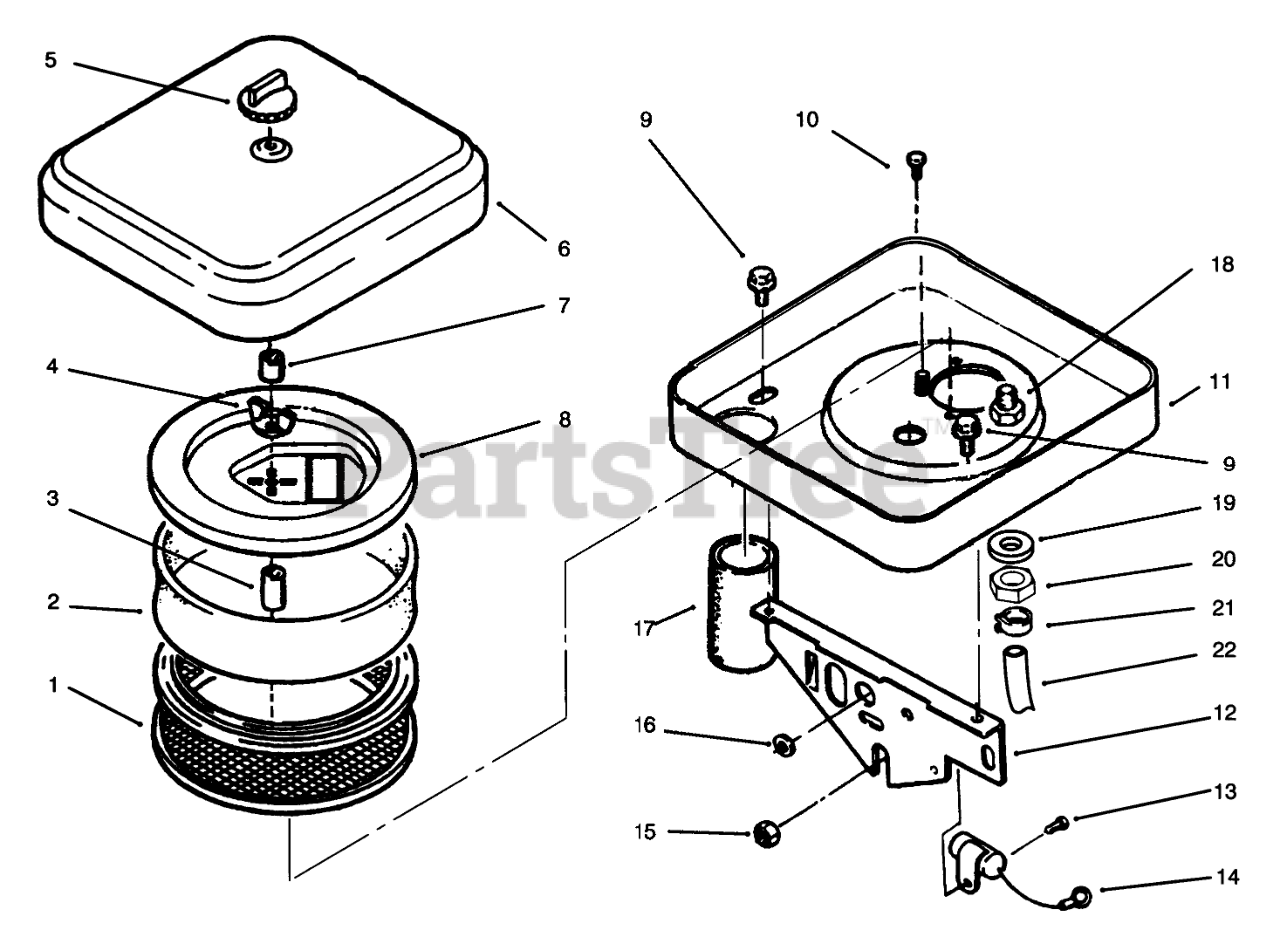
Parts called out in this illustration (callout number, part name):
1	AIR-CLEANER ELEMENT
2	AIR CLEANER ELEMENT
3	SPACER-1" LG
4	1/4-20 WING NUT
6	CHROME-AIR CLEANER
7	SPACER-RUBBER
8	ELEMENT COVER KIT
9	SCREW-TAPPING
10	MACHINE SCREW
11	AIR-CLEANER HOUSING
12	SUPPORT-AIR CLEANER
13	SCREW #10-32 X 5/8
14	CONDENSER
15	WASHER-LOCK
16	GROMMET
17	AIR INTAKE TUBE
18	Fitting-Barbed
19	HOSE FITTING GASKET
20	TAPPET NUT
21	CLAMP-HOSE
